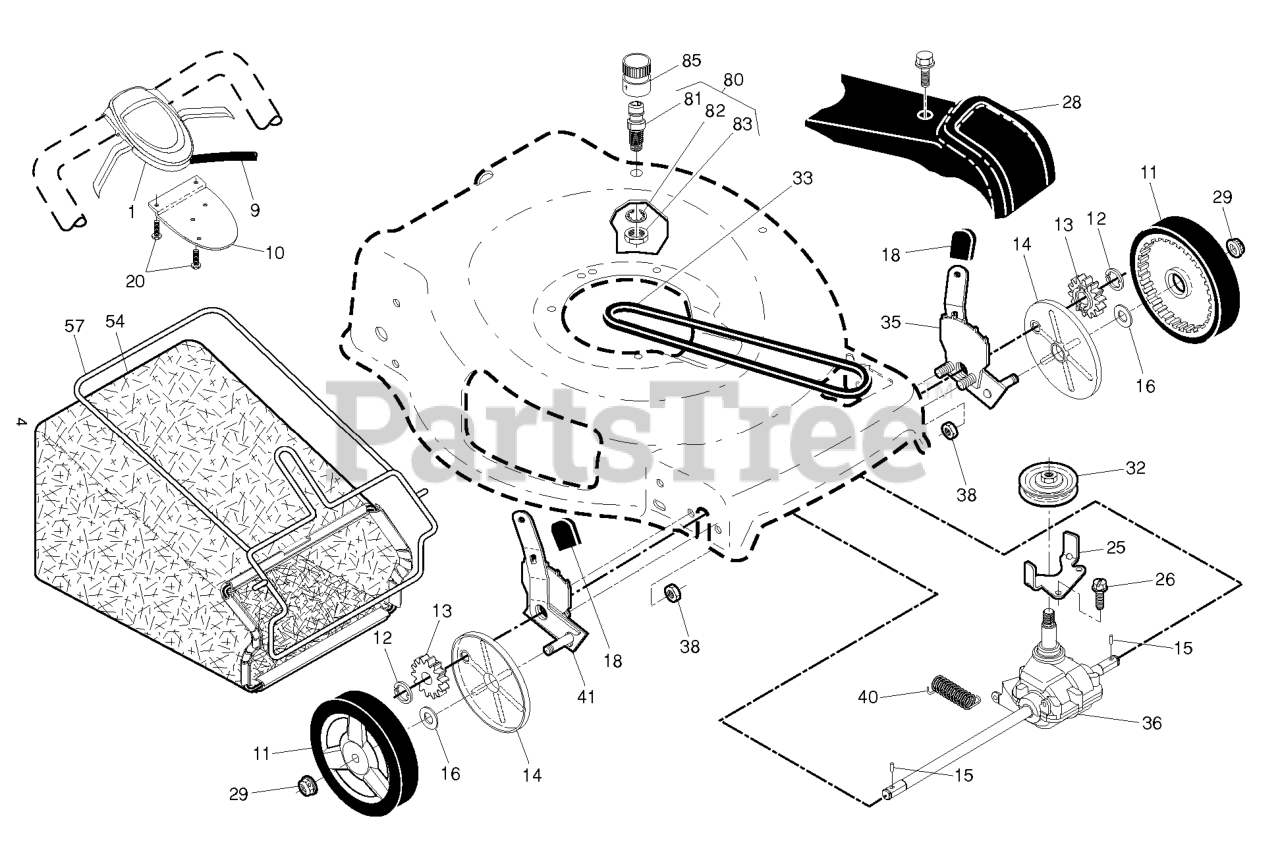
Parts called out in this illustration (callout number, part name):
1	CNTROL.AW22+FGD.ST.GEN.BLK/B
9	CABLE.CONTROL.22FGD.GEN2
10	BRACKET.DRIVE.CONTR.GEN2.BLACK
11	WHEEL.8X1.75.H3SPK.RAD3.GY.BU3
12	E-RING 7/16 RE
13	PINION.14.TEETH.FGD
14	COVER.DUST.WHEEL.INNER.WALK
15	PAWL, DRIVE
16	WASHER FLUT
18	SELECTOR KNOB
20	SCREW, PHILLIPS HEAD 10 X 5/8
25	BRACKET.BELT.GUIDE.22+FGD.BZP
28	COVER.DRIVE.22.LABEL.HUSQVARNA
28	COVER.DR.22.MB LABEL HUSQ E/F
29	NUT.HEX.FLANGE.3/8-16.LO(3 2)
32	RP PULLEY.DRIVE.EZ/VAR.SCREWON
33	BELT.DRIVE.FWD.
35	RP ADJ.ASM.9.22+/LF/RR.21/RF
36	RP.TRANSMISSION.22+.FWGD.SS
38	NUT.HEX.FLANGE.1/4
41	RP_ADJUSTER.ASM.9.22+/RF/LR.21
54	GBAG.A361029ER.HUSQ.GRY/SIL
57	FRAME.GBAG.22+.BLK
80	KIT.WASH-OUT.PORT.ZINC.WALK
81	WASHOUT.PORT.ZINC.RGD.22+
82	WASHER.LOCK.INTERNAL.TOOTH
83	LOCKNUT.HEX.WITH.O-RING
85	COUPLING.QUICK CONNECT
